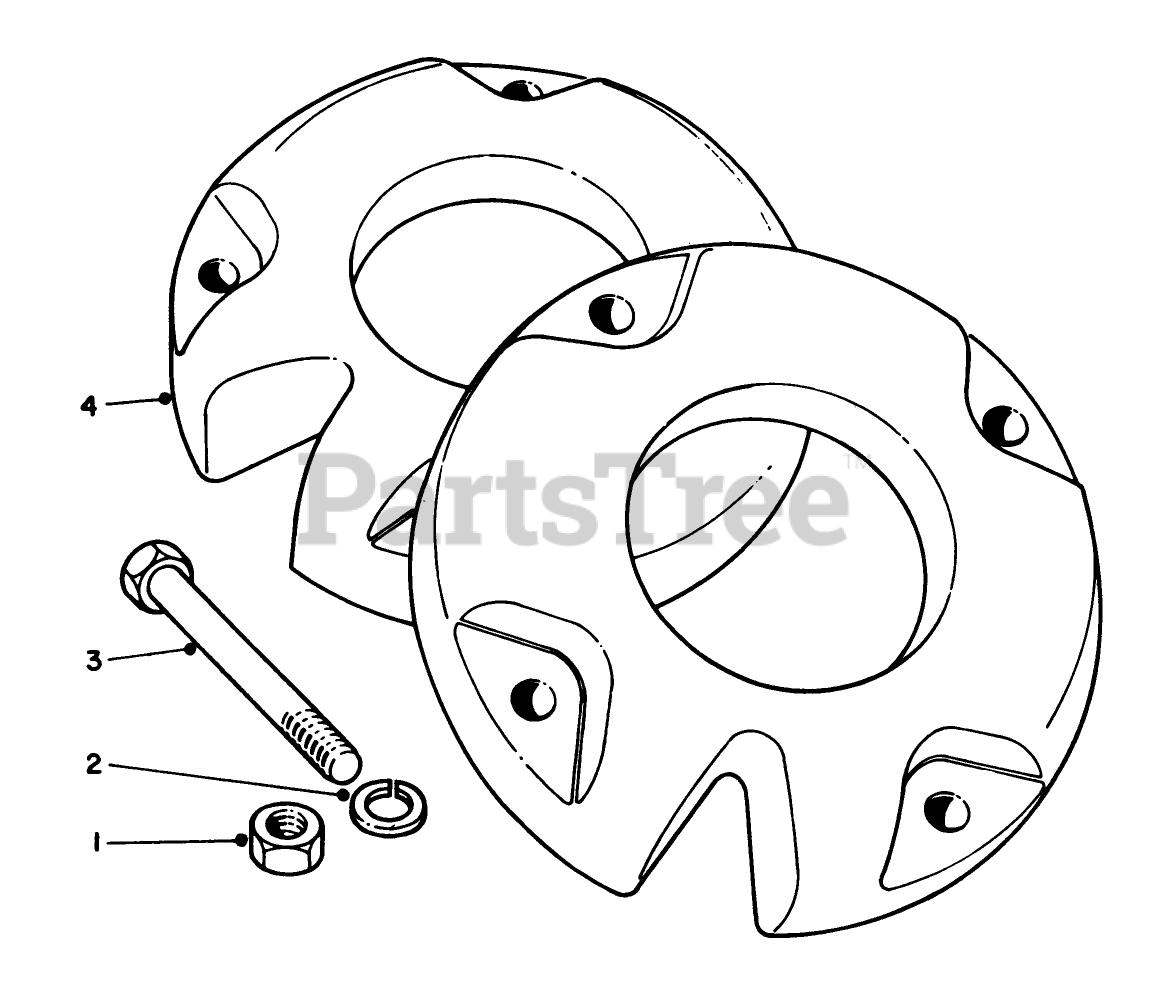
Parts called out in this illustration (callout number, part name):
1	NUT-JAM
2	WASHER-LOCK
3	SCREW-HH
4	Weight-Wheel
